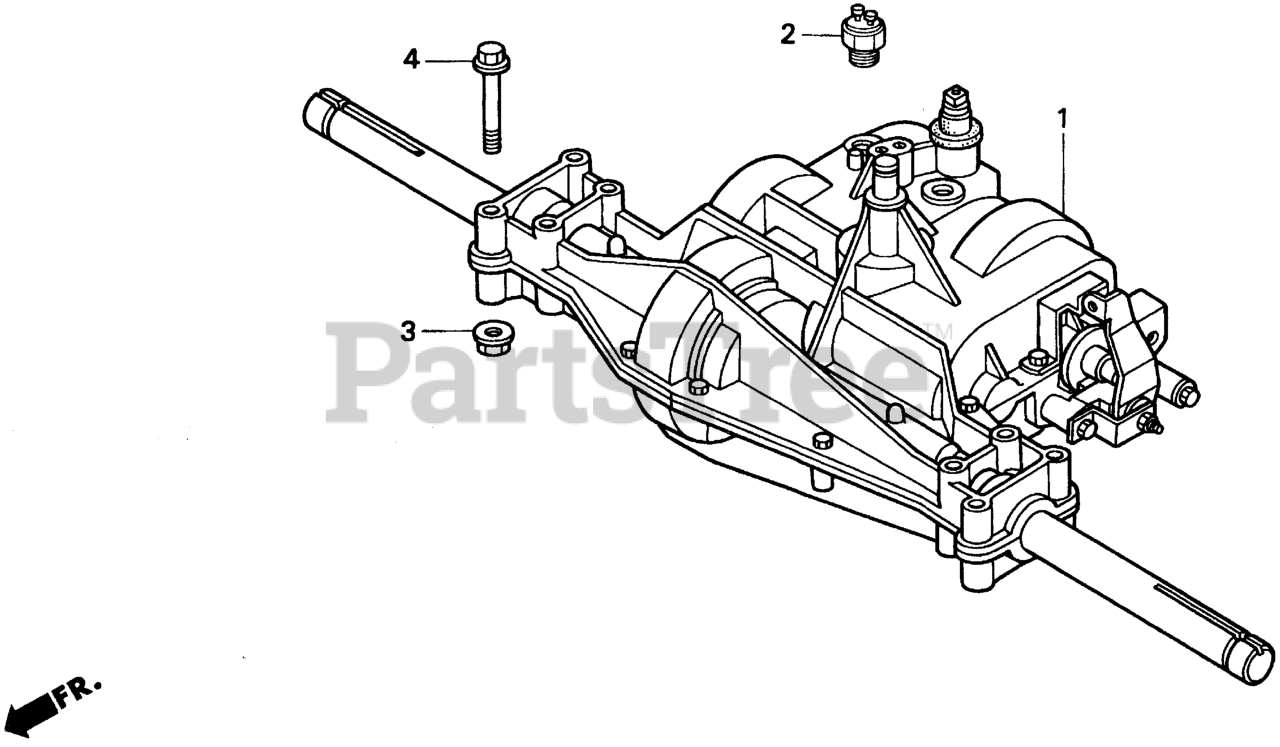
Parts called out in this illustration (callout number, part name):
1	TRANSMISSION ASSY.
2	SWITCH ASSY., NEUTRAL
3	NUT, FLANGE (8MM)
4	BOLT, FLANGE (8X65)
